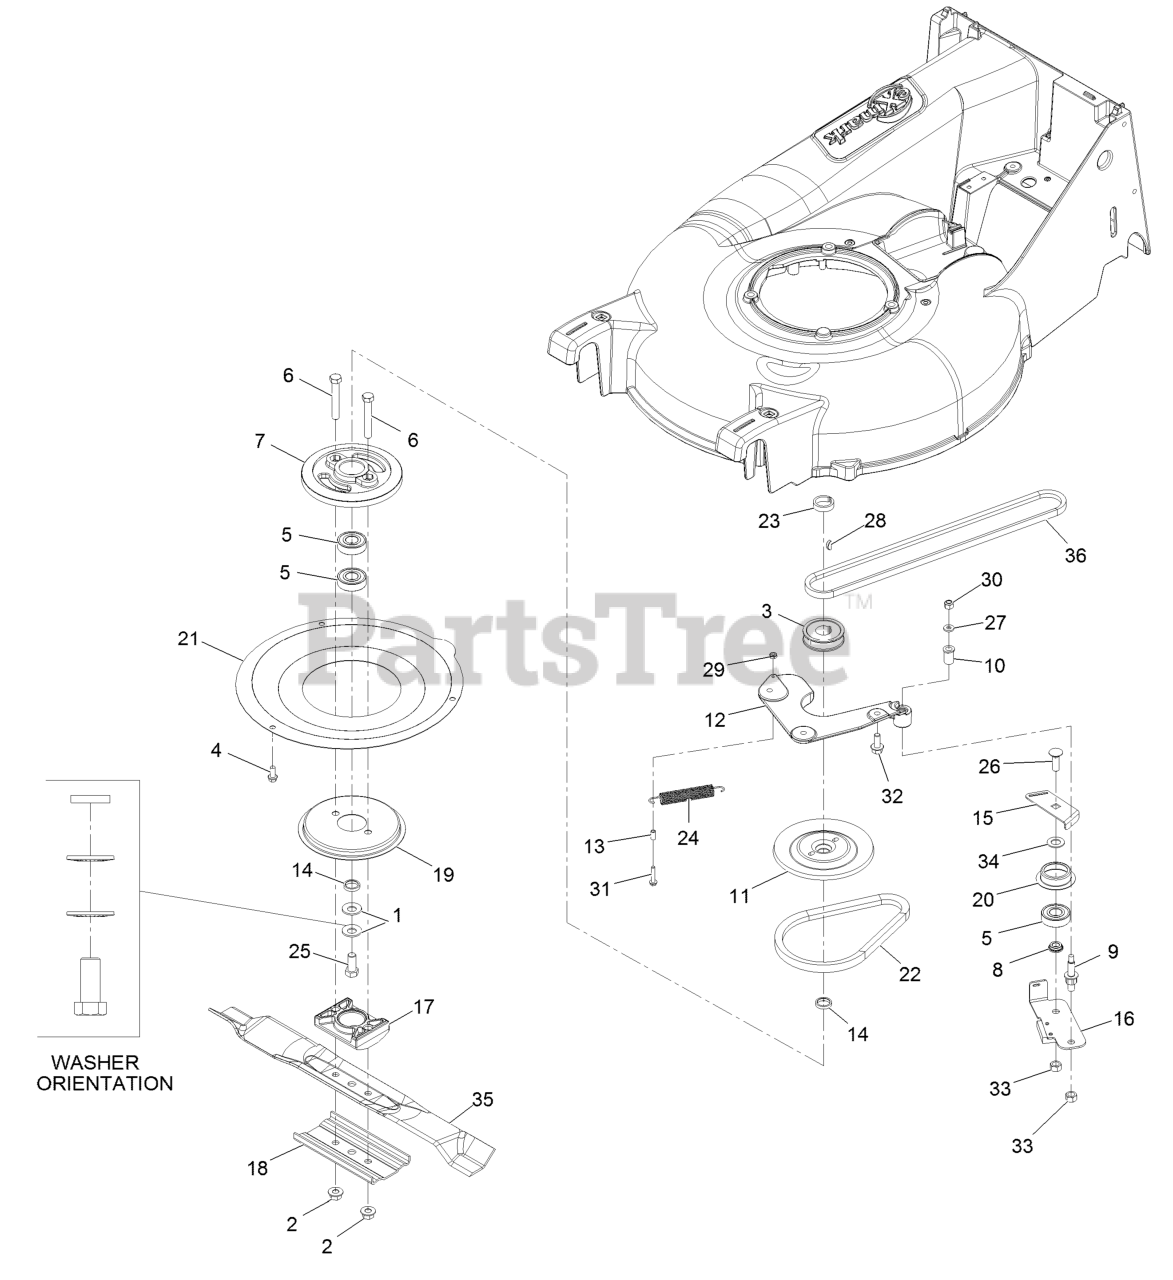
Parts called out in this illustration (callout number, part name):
1	WASHER-SPRING
2	NUT-FLANGE, LOCK
3	PULLEY-DRIVER
4	SCREW-HWH
6	SCREW-HH
8	SPACER-BEARING
9	BOLT-SHOULDER
10	BUSHING
11	PULLEY-DRIVER, UPPER
12	PLATE-MOUNTING, BBC
13	SPACER-BBC
14	SPACER-PLATE, BBC
15	PLATE-GUIDE
16	PLATE-BRAKE
17	SUPPORT-BLADE
18	SUPPORT-BLADE
19	DISC
20	RETAINER-BELT
21	COVER-BBC
22	BELT
23	SPACER-PULLEY
24	SPRING-EXTENSION
25	SCREW-HH
26	SCREW-CARR
27	WASHER-FLAT
28	KEY-WOODRUFF
29	NUT-LOCK, NI
30	NUT-LOCK, NI
31	SCREW-TAP
32	SCREW-HHF
33	NUT-HEX
34	SPACER
36	BELT,3L P21 DRIVE
